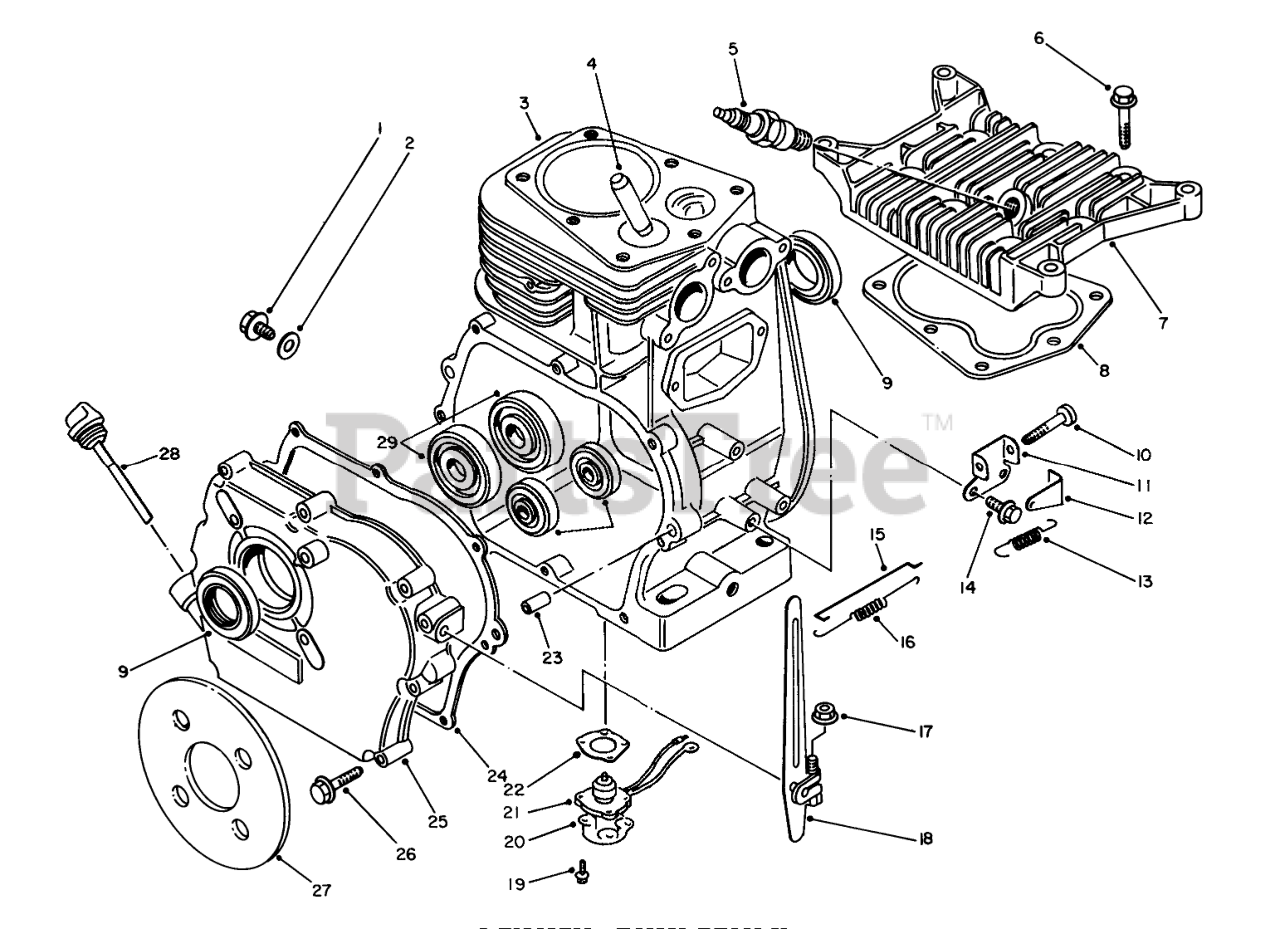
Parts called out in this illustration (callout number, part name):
1	Drain Plug
2	GASKET
3	Cylinder
4	Guide Valve
7	Cylinder Head
8	GASKET
9	Oil Seal
11	Bracket
13	SPRING
15	Rod-Carburetor
16	SPRING
18	Lever-Control
20	Plate
21	SENSOR
22	GASKET
24	Gasket-Crankcase
25	Cover-Crankcase Side
27	Seat-Joint
28	Gauge-Oil Level
29	Bearing
